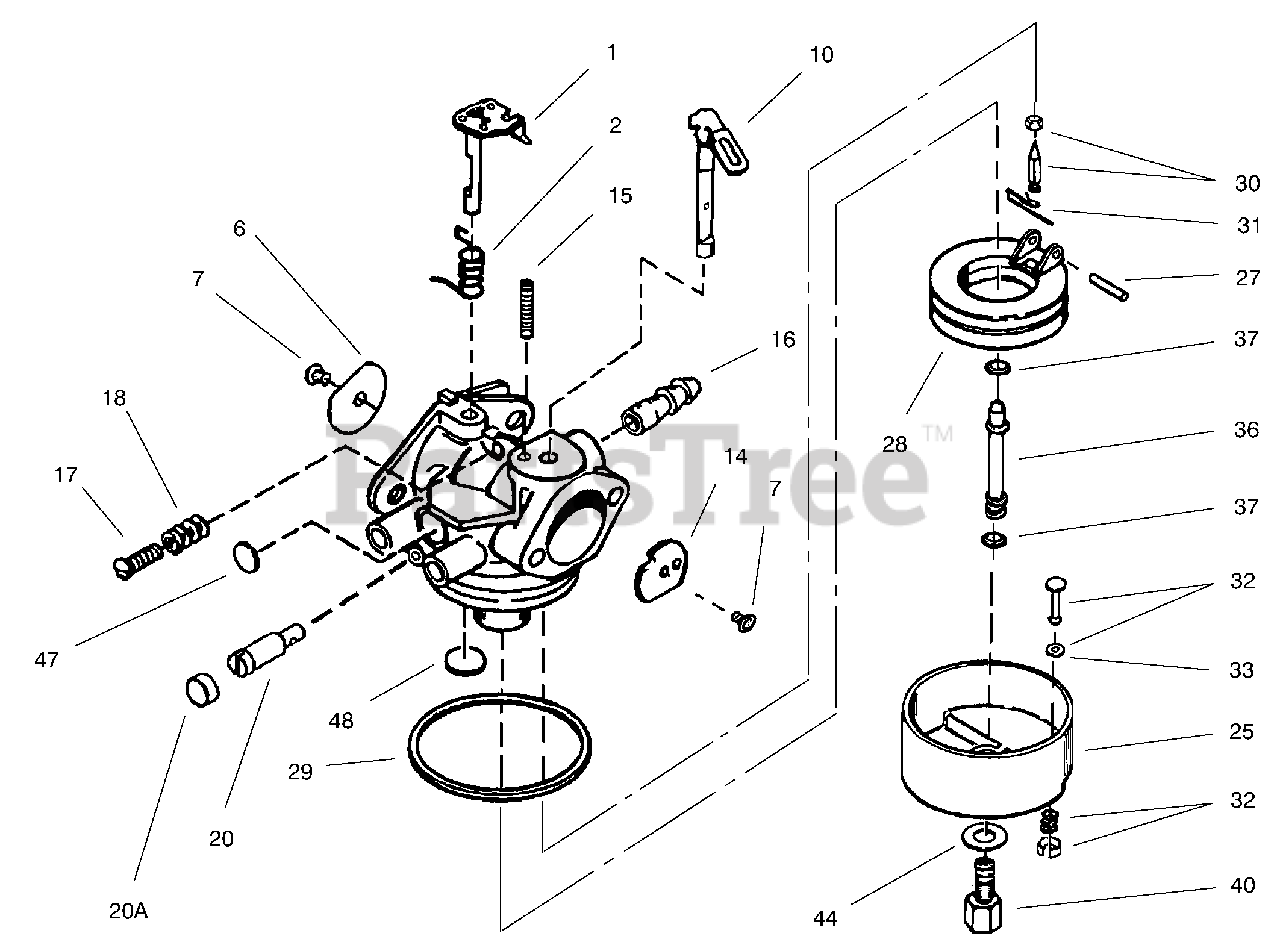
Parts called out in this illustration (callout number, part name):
1	Shaft/Lever-Throttle
2	Spring-ThrottleReturn
6	Shutter-Throttle
7	Screw-Shutter
10	Shaft/Lever-Choke
14	Shutter-Choke
15	Spring-ChokePositioning
16	Fitting-Fuel Inlet
17	Screw-IdleRegulating
18	Spring-Tension
20	Screw-IdleAdjustment
21	Cap-Screw Idler Adj.
25	Float Bowl Assembly (Incl. Ref. #32 & 33)
27	Shaft-Float
28	Float-Carburetor
29	Gasket-Bowl toBody
30	Inlet Needle, Seat &Clip Asm (Incl. Ref. #31)
31	Clip-Inlet Needle
32	Drain Assembly (Incl. Ref. #33)
33	Gasket-Bowl Drain
36	Main Nozzle Tube
37	O-Ring-Main NozzleTube
40	High Speed Bowl Nut
44	Gasket-Bowl toBody
47	Plug-Welch
48	Plug-Welch
